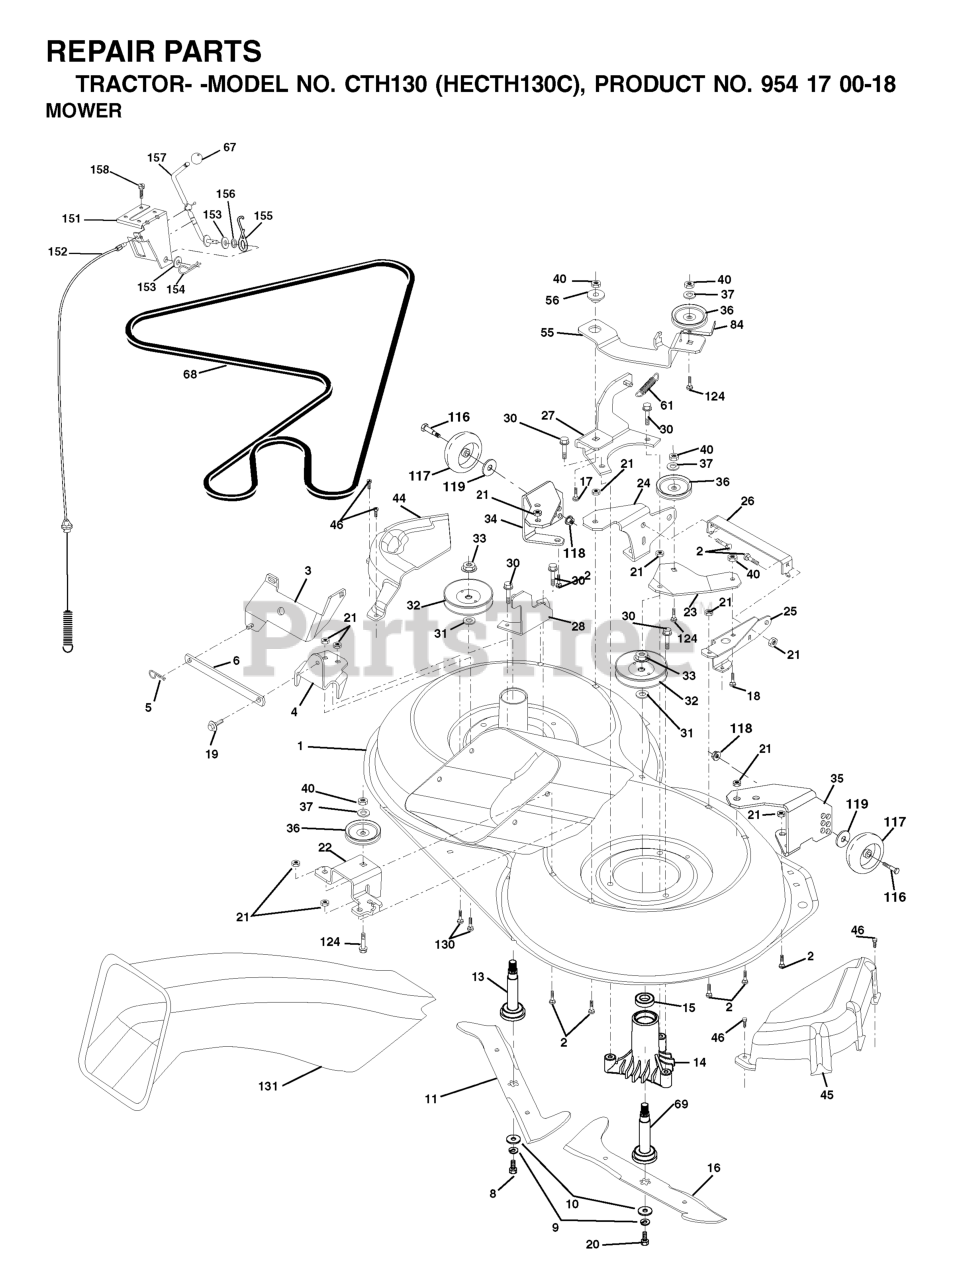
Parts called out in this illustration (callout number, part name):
1	MOWER HOUSING, DECK
2	RP BOLT 5/16-18 X3/4 ZN/YEL GR
5	RETAINER-SPRNG RB
6	BAR.SWAY.92.CRD
8	BLADE BOLT
9	LOCKWASHER
10	WASHER.BLADE
11	BLADE-LH 5PT STAR(CTH130)
12	BEARING.BALL.#6204.(MANDREL)
13	SHAFT ASM VENT
14	HOUSING.MANDREL.VENTED (MACHD)
16	BLADE RH 6PT STAR(CTH130)
17	BOLT.3/8-14X1.25
18	BOLT D
19	BOLT SHD 5/16-18
21	LOCKNUT
26	BRACE.SUPT.SUSP.FRT.CRD
30	SCREW THDROL ROLLING WASHER HD
31	WASHER
32	PULLEY, MANDREL
33	NUT
36	PULLEY.IDLER.4.25
37	WASHER
44	COVER.MANDREL.LH.92.CRD
45	COVER
46	SCREW.1/4-20X5/8
56	SPACER.RETAINER.MOWER
61	SPRING.TENSION.BELT
67	KNOB T (3/8 HOLE)
68	HEX-BELT 92 MOWER 105AA
69	SHAFT.ASM.W/LWR.BRG.RH.THREAD
84	KEEPER, BELT IDLER
116	BOLT, SHOULDER
117	WHEEL GAGE DONUT
118	LOCKNUT
119	WASHER.5/16.FLAT.STE.STD.
124	BOLT.3/8-16X1.50
128	WASHER FELT
130	BOLT.CARR.SQNK.5/16-18UNC.X3/4
131	CHUTE BAGGER
151	BRACKET.CLUTCH.CABLE
152	Cable Clutch CRD Service
153	WASHER FLAT 3/8"
154	SPRING RETAINER
155	SPRING RETENTION LEVER
156	SPACER.CLUTCH.CABLE
157	ROD CLUTCH CABLE 3/8"
158	SCREW LT
